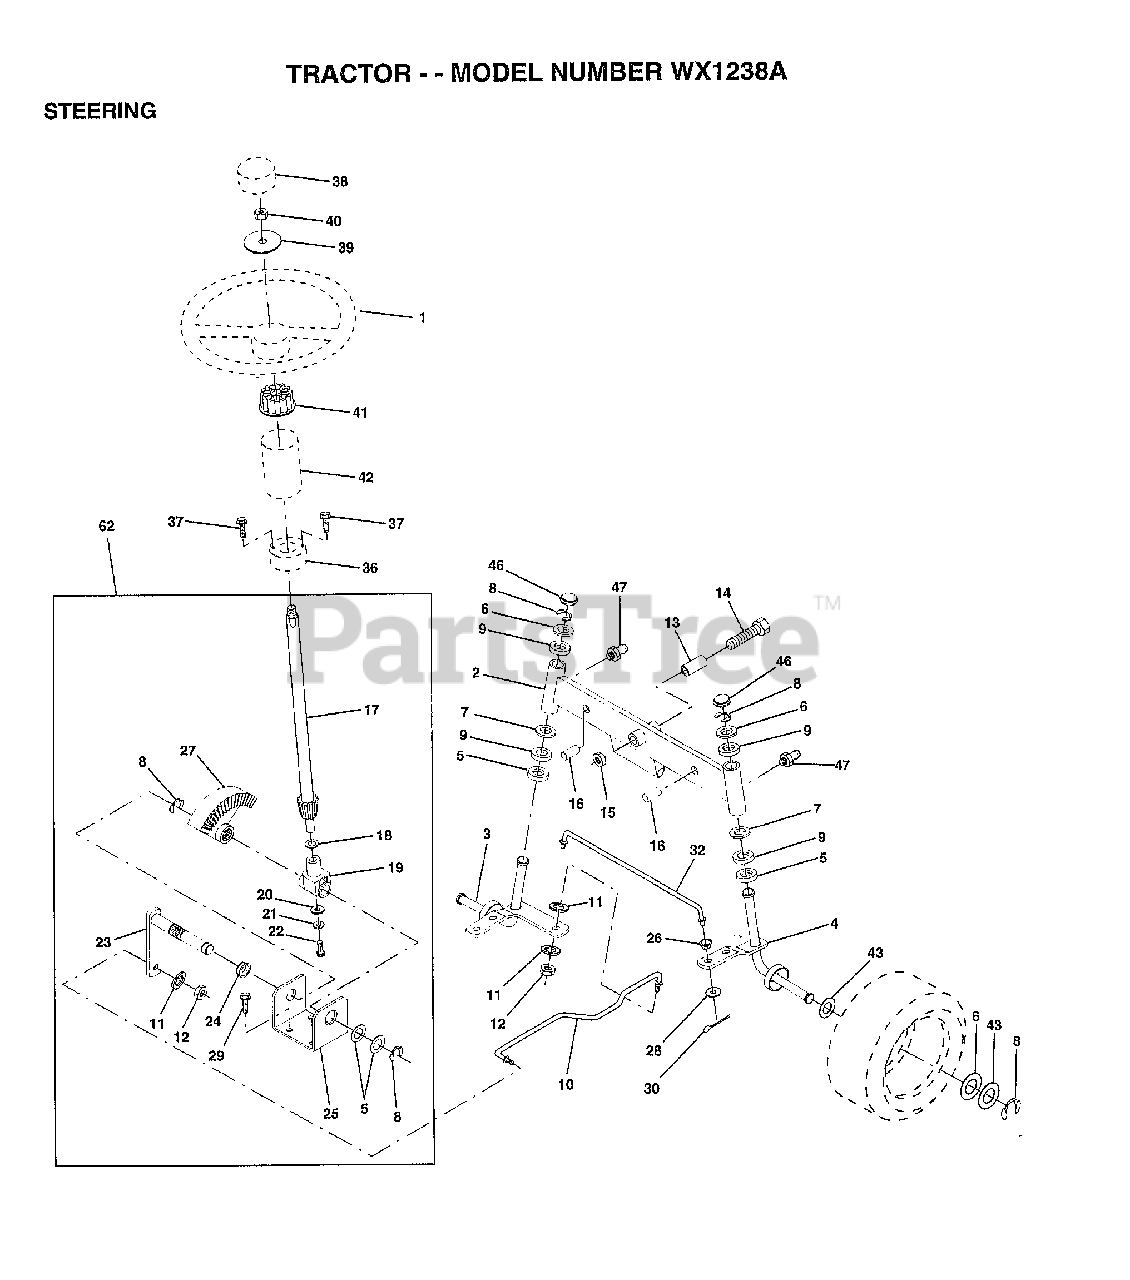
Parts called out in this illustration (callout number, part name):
2	AXLE ASM FRONT
3	SPINDLE LH
4	SPINDLE RH
5	WASHER .T
6	WASHER
7	WASHER
8	RING
9	COL. SRTG. BEAR.
11	LOCKWASHER
13	BEARING
14	BOLT HEX 5/8-11
15	"NUT-LOC,FLANGE LT"
16	AXLE PIN
17	SHAFT ASM
18	THRUST WASHER
19	SUPPORT.SHAFT
21	LOCKWASHER
22	"SCREW,SPECIAL"
24	NYLINER T
25	"BRKT,STEERING"
26	BUSHING.DRAGLINK
27	GEAR SECTOR
28	WASHER
29	SCREW
30	COTTER PIN
32	TIE ROD
38	ST WHL INSERT CAP
39	WASHER T
40	GRIPCO NUT
41	ADAPTER-WHEEL LT
42	"TUBE, STR SHAFT"
43	WASHER
46	CAP
47	ZERK M
62	STEERING.ASM.LT
